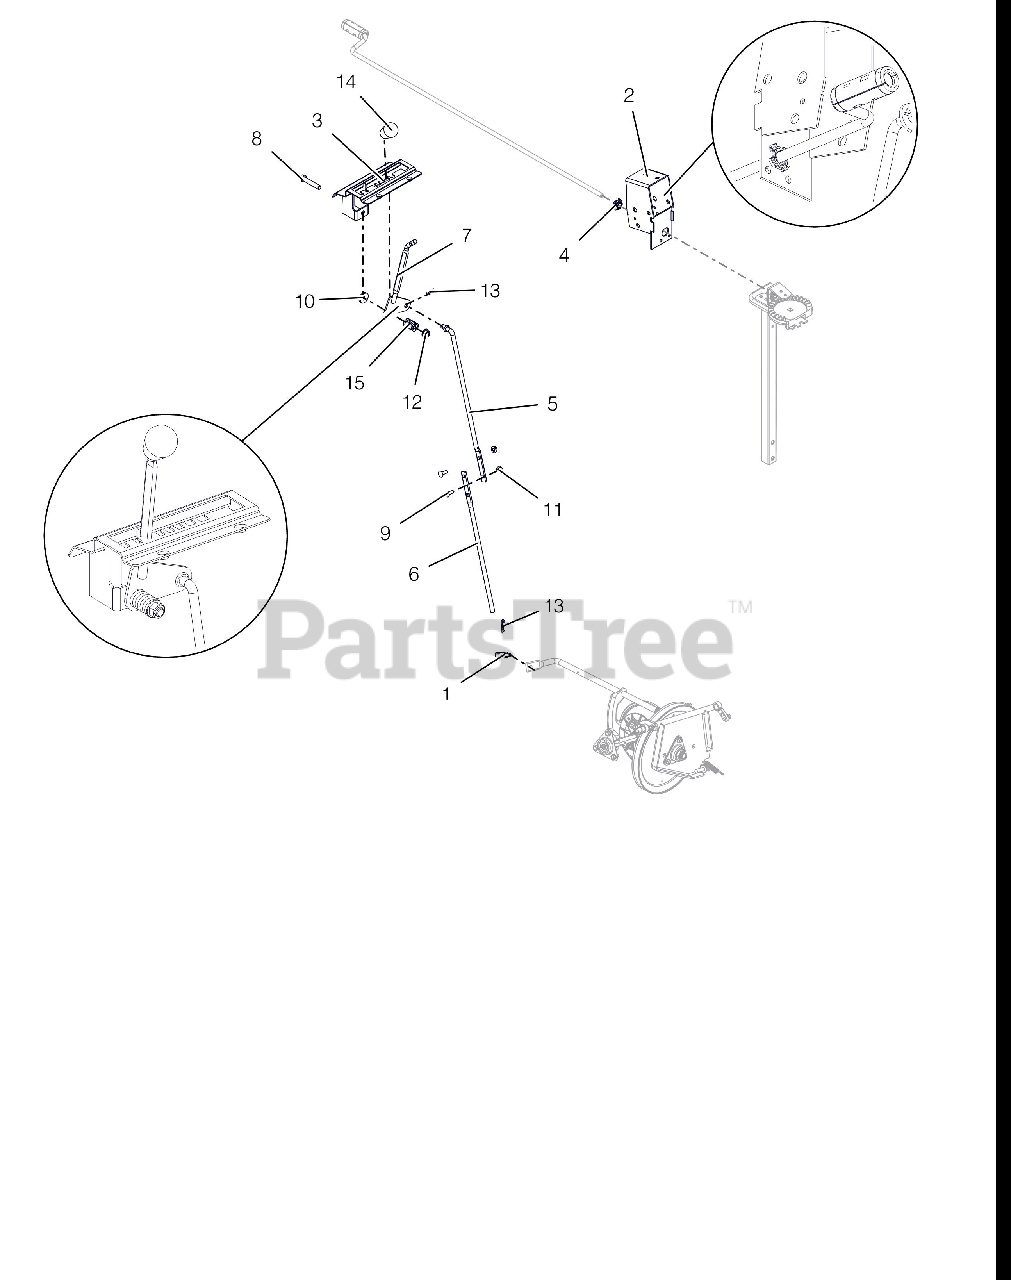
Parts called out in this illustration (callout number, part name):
1	PIVOT,SHIFT ROD .375-16(TRUNN)
2	WELDMENT, BRACKET INTERLOCK
3	WELDMENT, DETENT PLATE-COMPACT
4	CRANK BUSHING, NYLON CHUTE BK
5	ROD, SHIFT - UPPER
6	ROD, SHIFT - LOWER(SMALL DASH)
7	LEVER, CONTROL-SHIFT(WELDMENT)
8	@BLT-HEX .38-16X2.00 GR5 YWZC
9	@BLT-RDHDSQNK .25-20X.75 G5YZ
10	WSHR-FL-STL .406X1.00X.188 YWZ
11	@NUT-LK-CTR-FLG .25-20 YWZC
12	@NUT-LK-TOP-FLG .38-16 YWZC
13	PIN-HAIR INT .08X.18X1.18 YWZC
14	KNOB,SOFT TEARDROP,PUSH-ON BLK
15	SG-COMP .125X.781X1.250
